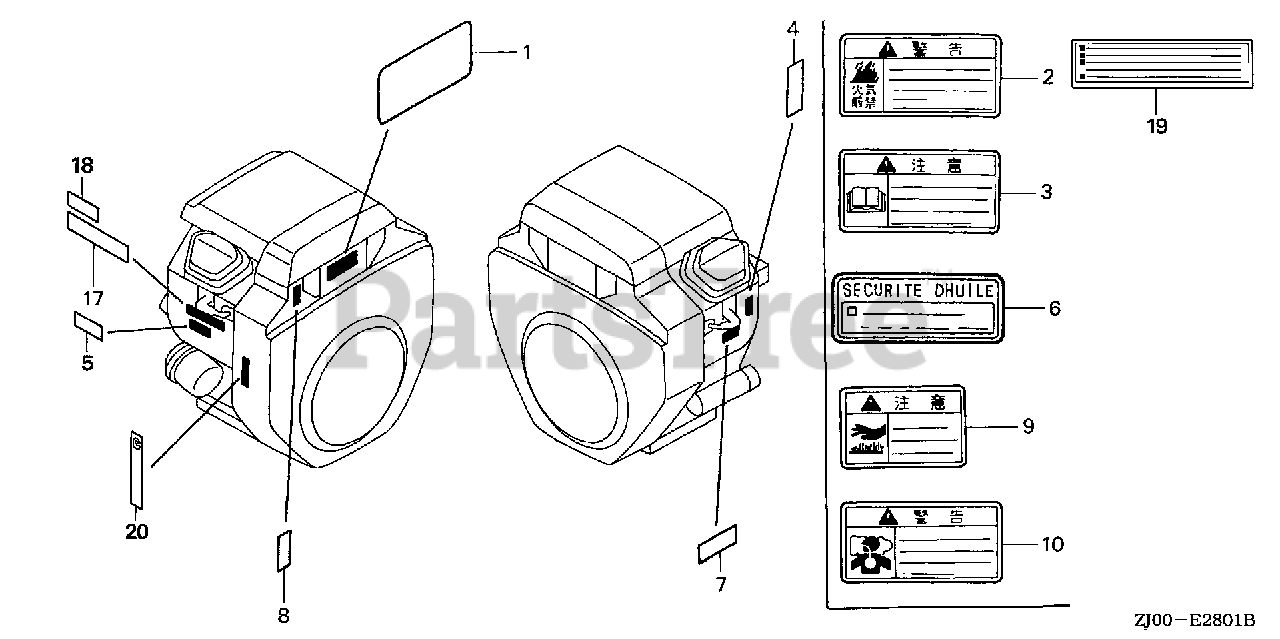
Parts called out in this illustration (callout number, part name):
1	EMBLEM (GX610)
2	MARK, FUEL WARNING
3	MARK, CAUTION (JAPANESE)
4	LABEL, SPECIFICATION (GX610)
9	MARK, HEAT CAUTION
10	MARK, EX. GAS WARNING
